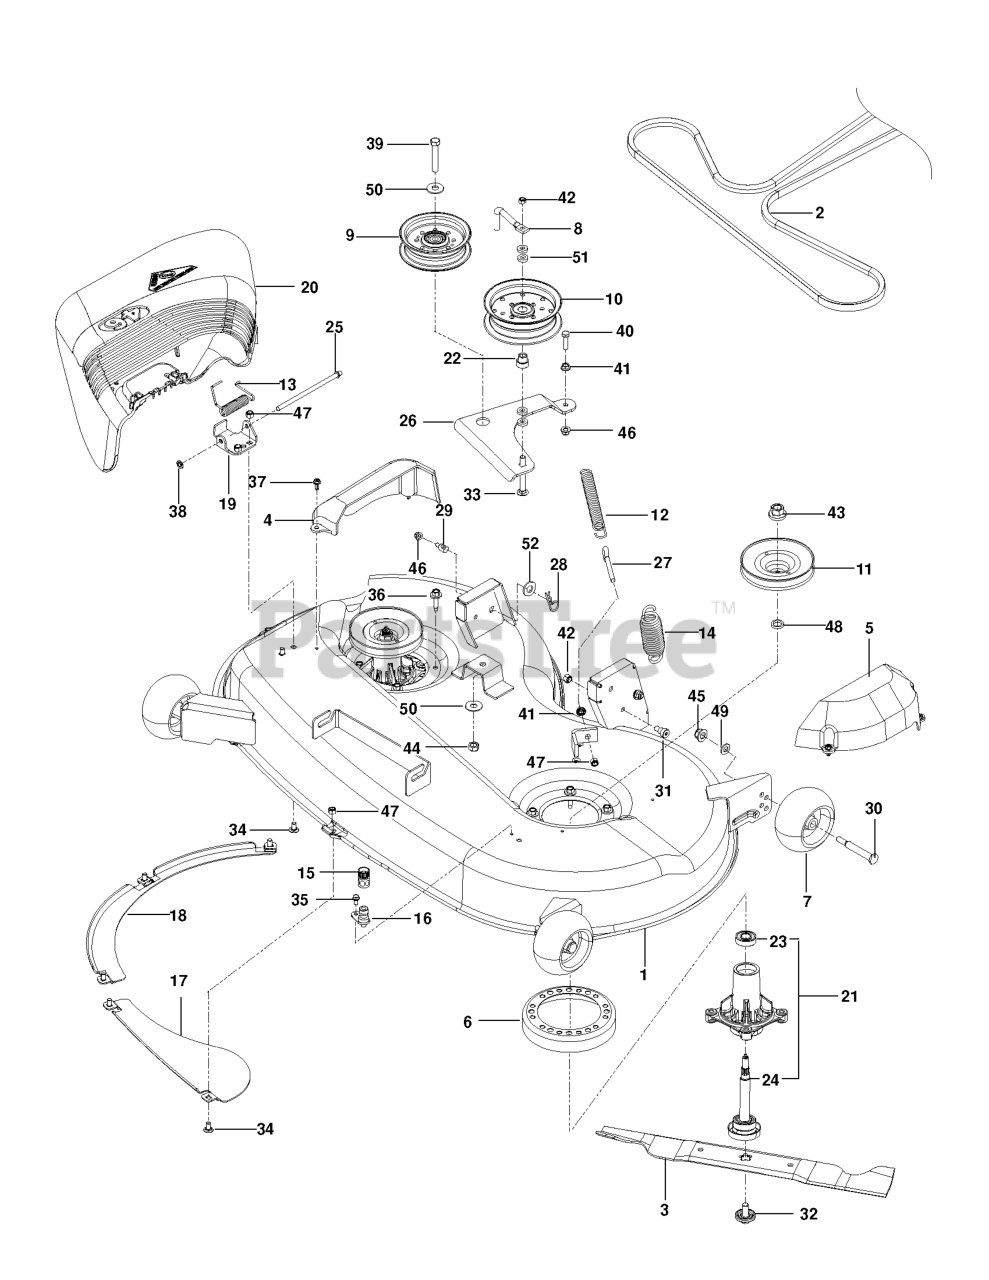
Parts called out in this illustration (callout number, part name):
1	DECK SVC 46"W/DECALS ORG
3	BLADE.MOWER.46".HI.LIFT
4	COVER.MANDREL.RH.46"
5	COVER.MANDREL.LH.46"
6	STRIPPER.MANDREL.ROUND.BLACK
7	RP WHEEL. GUAGE RALLY
8	BELT KEEPER 5"
9	PULLEY.IDLER.MWR.STATI.LH
10	PULLEY, IDLER
11	RP.PULLEY, DECK
12	SPRING, DECK BELT
13	SPRING, TORSION
14	SPRING
15	COUPLING.QUICK CONNECT
16	PORT.WASHOUT
17	BAFFLE CENTER FRONT
18	BAFFLE FRONT RH
19	BRKT.DEFLECTOR.38"2005+
20	SHIELD.DEFLECTOR.MOWER.46"BLAC
21	MANDREL ASM
22	IDLER BUSHING
24	SHAFT ASM W/LOWER BEARING
25	ROD, HINGE
26	ARM, IDLER BLK
27	EYE BOLT 5/16 X 3.50
28	HAIRPIN #4
29	STUD.FASTNER.W/ANTI-ROTATE
30	BOLT.SHOULDER.3/8-16X3-5/8.
31	SB 3/8-16 X 3/8 SKT HD ZD
32	BOLT.WASHER.ASM.7/16-2
33	CARRIAGE BOLT 3/8-16 X
34	RP BOLT 5/16-18 X3/4 ZN/YEL GR
35	SCREW #10 X 1/2 SELF TAPPING
36	SCREW, WASHER HEAD
37	SCREW.1/4-20X5/8
38	NUT PUSH M
39	BOLT 7/16-14 X 2-1/2 GR 5 ZD
40	BOLT.5/16-18X1-1/4 FULL.THREAD
41	NUT 5/16C WHIZ
42	NUT HEX 3/8-16 NYLON, THIN
43	NUT.FLANGE.LOCK.TOP
44	7/16-14 HEX NUT W/NYL RING ZD
45	NUT 5/16C WHIZ
45	NUT LOCK FLG 3/8-16 UNC
46	5/16-18 NYLOC FLANGE NUT
47	NUT.71038.31-18.HEX.NYLOCK
48	WASHER.SPACER.MANDREL
49	WASHER
50	WASHER 7/16 FLAT ZD
51	WASHER 3/8 X 3/4 X .187 TK
52	WASHER
